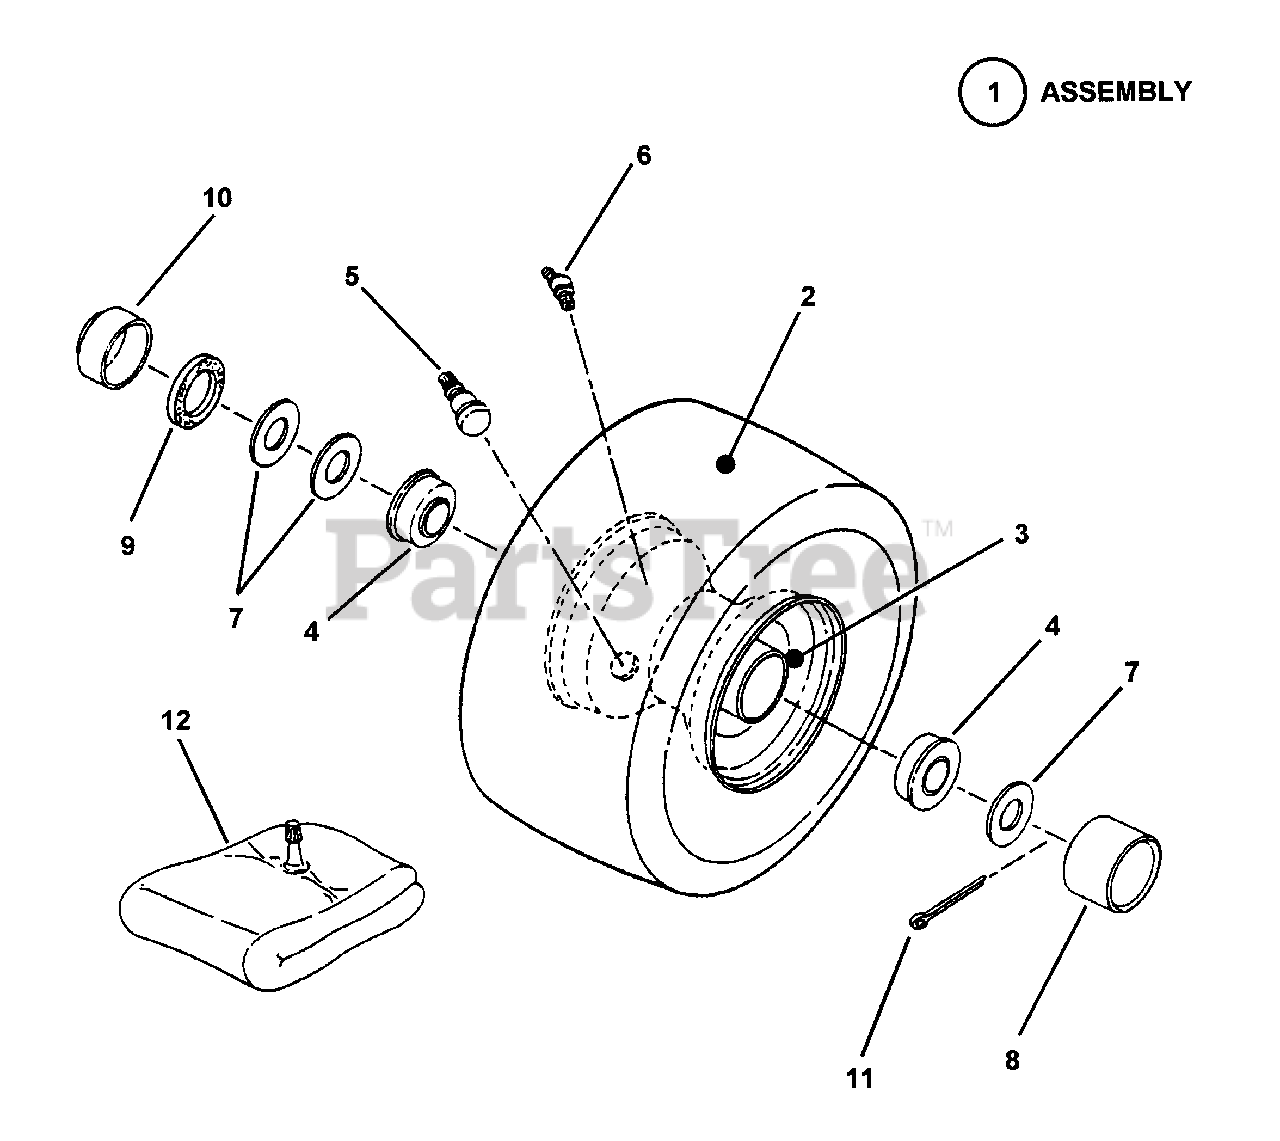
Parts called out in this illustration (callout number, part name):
1	ASSEMBLY, Front Tire & Rim
2	TIRE, Pneumatic 4.10/3.50 x 4
3	RIM
4	BEARING, Ball
5	VALVE, Air (Snap-in)
6	FITTING Lube
7	WASHER
8	CAP, Hub
9	SEAL, Felt
10	CAP, Dust
11	PIN, 5/32 x 1" Cotter
12	TUBE, Inner
